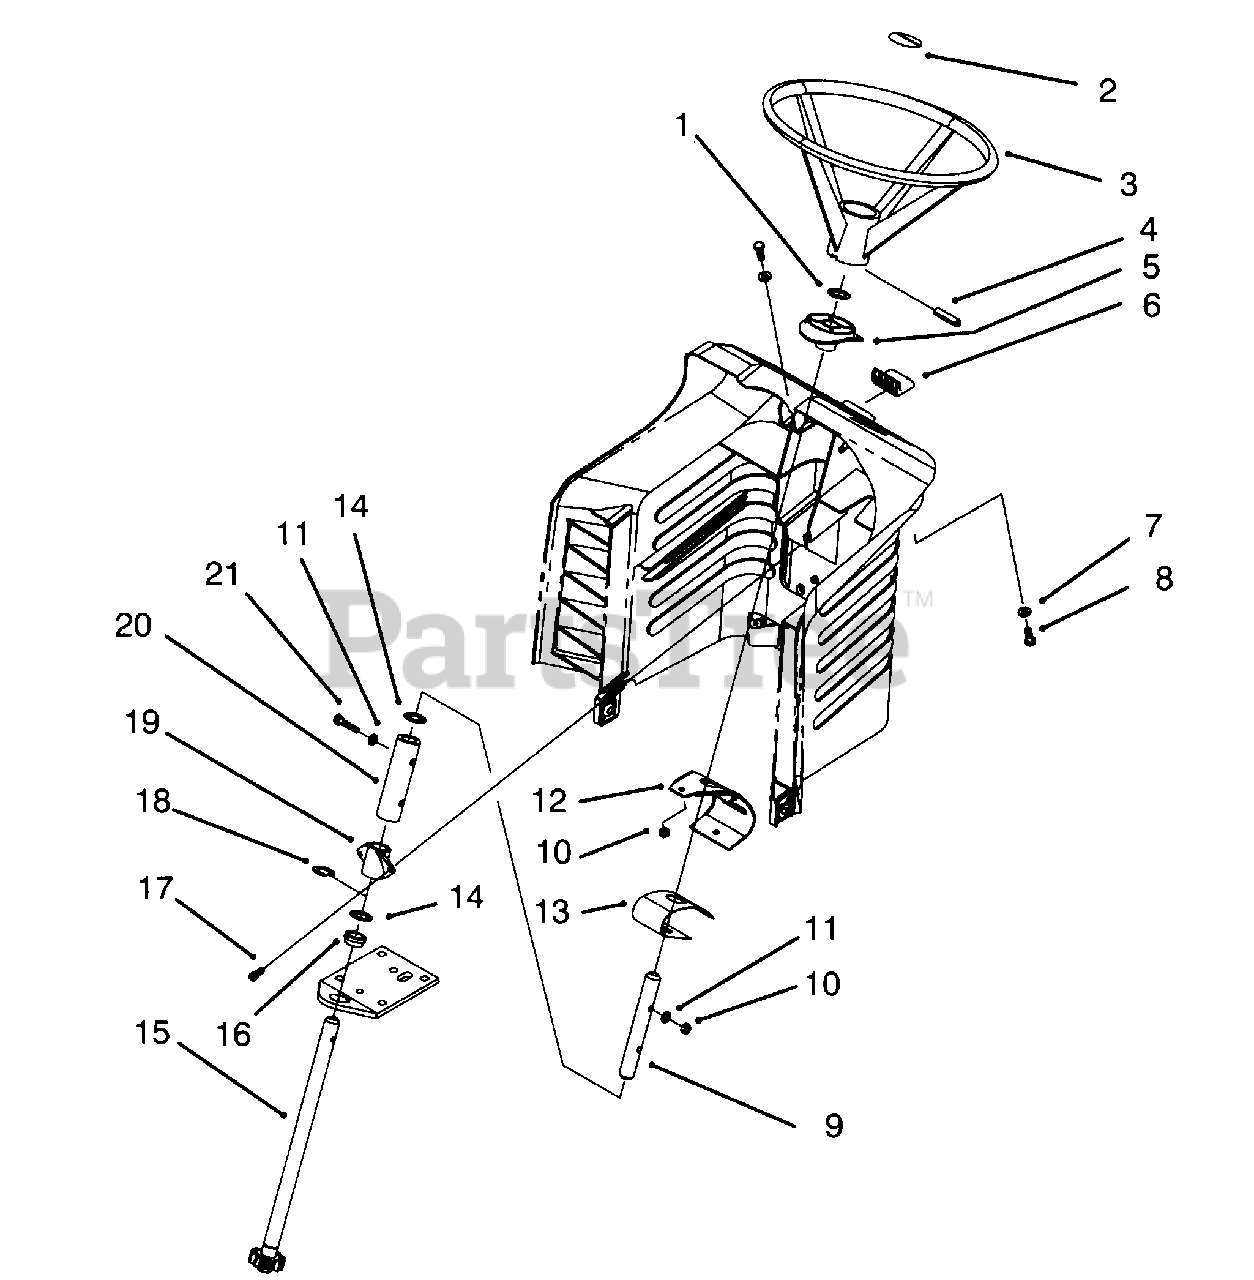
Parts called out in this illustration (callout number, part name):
1	Ring-Retaining
2	Insert-Steering Wheel
3	Wheel-Steering (Incl. Ref. #2)
5	Bushing-Sliding
6	Button-Release
7	Washer-Flat
8	Screw-Hex Hd. Cap
9	Shaft-Steering Upper
10	Nut-Lock
11	Washer-Curved
12	Bracket-Backup
13	Spring-Leaf
14	Washer-Thrust
15	Shaft-Steering Short
16	Bushing-Flange
17	Screw-Plastite
19	Bushing-Stationary
20	Coupling-Steering
21	Screw-Hex Hd. Cap
